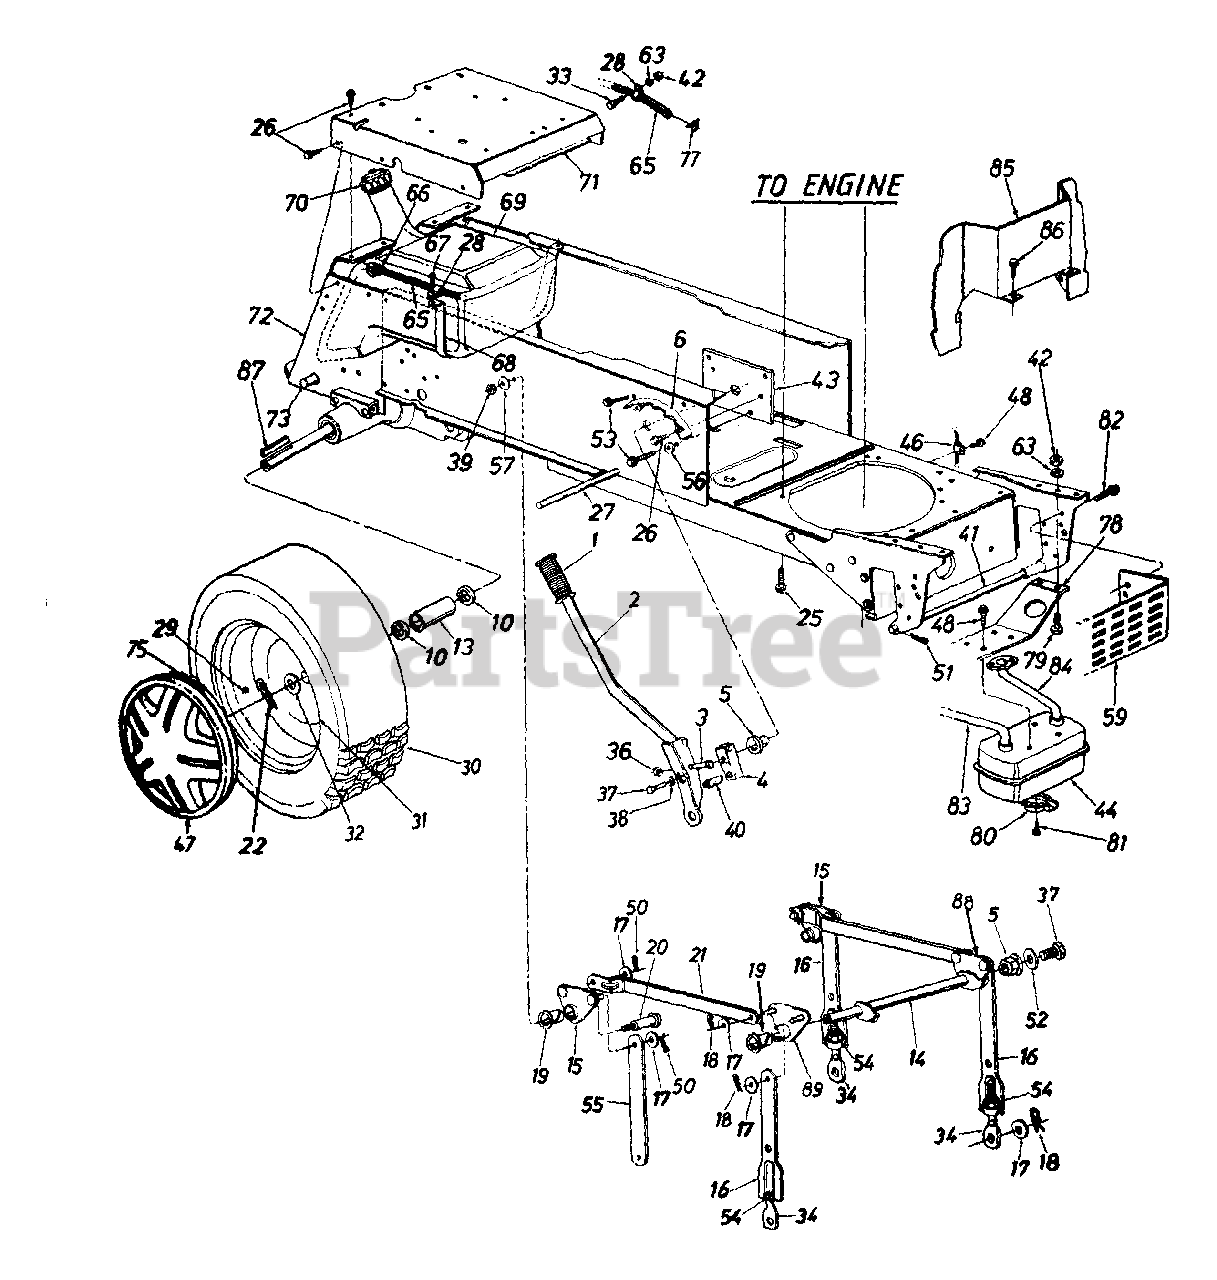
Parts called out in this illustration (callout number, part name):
1	Grip
2	Lift Handle Ass'y.
3	Hex Bolt 5/16-18 x 1.5" Lg."
4	Lift Shaft Drive
5	Plastic Hex Brg. 5/8" I.D.
10	Fl-Wash. 1.03" I.D. x 1.62" O.D.
13	Spacer 1" I.D. x 1.25" O.D.
14	Lift Shaft Ass'y.
15	Lift Pivot Brkt. Ass'y.
17	Fl-Wash. 1/2" I.D. x 1.00" O.D. x .090"
18	Hairpin Cotter
19	Flanged Brg. 5/8" I.D.
20	Shld. Bolt 5/8" Dia. x .96" Lg. 3/8-16
25	Hex Wash. Hd. Scr. 3/8-16 x 1.25" Lg.
26	Hex Thd. Rolling Scr. 5/16-18 x .75" Lg.
27	Running Board Rod
29	Air Valve
33	Hex Bolt 1/4-20 x .62" Lg.
34	Eye Bolt Adj. Link 1/2-13 Thd.
36	Hex Cent. L-Nut 5/16-18 Thd.
37	Hex Bolt 5/16-24 x .75" Lg. (Gr. 5)
39	Hex Top L-Nut 3/8-16 Thd.
40	Compression Spring
41	Deck Connecting Rod
42	Hex Nut 1/4-20 Thd.
46	Mounting Clamp
47	Hub Cap
48	Hex Wash. Hd. TT-Tap Scr. 1/4-20 x .5" Lg.
50	Cotter Pin .09 Dia. x 1.0" Lg.
51	Int. Cotter Pin
52	Flat Wash. .34" I.D. x 1.12" O.D. x .125"
53	Hex Wash. Hd. AB-Tap Scr. 5/16-18 x .5" Lg.
54	Hex Nut 1/2-13 Thd.
56	Fl-Wash. .344" I.D.
57	Bell-Wash. .4" I.D. x 1.13" O.D.
59	Heat Shield
63	L-Wash. 1/4" I.D.
65	Fuel Line 46" Lg.
67	Hex AB-Tap Scr. 1/4 x .62" Lg.
68	Fuel Tank Strap
75	Spring Clip
78	Muffler Mounting Brkt.
79	Hex Bolt 1/4-20 x .62" Lg.
80	Muffler Deflector
81	Hex Wash. Hd. F-Tap Scr. #8 x .32" Lg.
82	Hex Wash. Hd. TT-Tap Scr. 5/16"-18 x .62" Lg.
83	Exhaust Tube - R.H.
84	Exhaust Tube - L.H.
87	Sq. Key 1/4" x 3" Lg.
88	Lift Pivot Brkt. - L.H.
89	Lift Pivot Brkt. - R.H.
